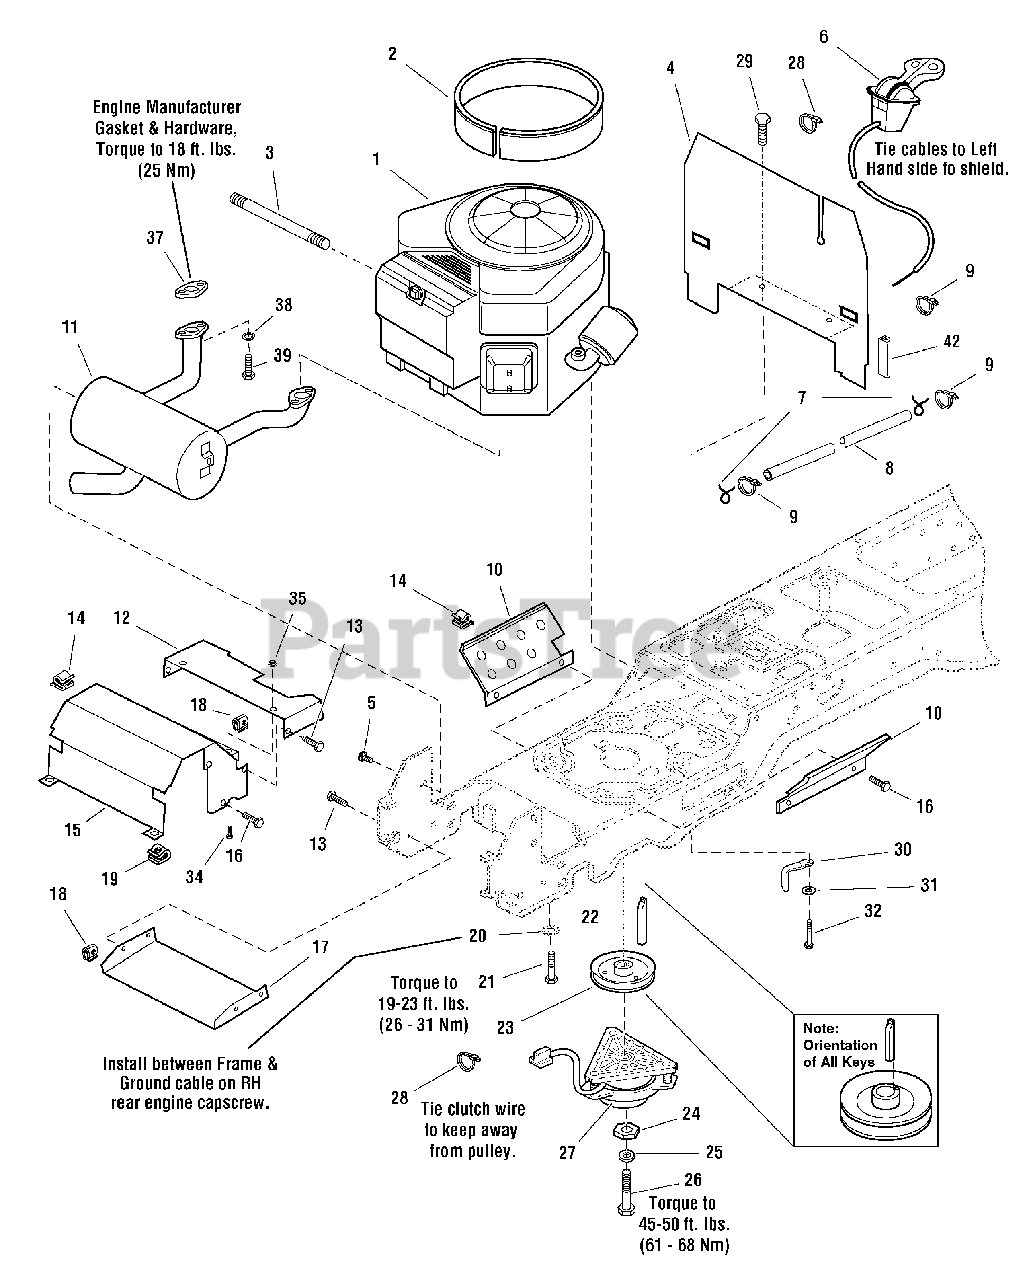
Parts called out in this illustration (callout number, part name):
1	* ENGINE, 24HP Briggs & Stratton Pro Series Twin
1	* ENGINE, 26HP Briggs & Stratton Professional Series
2	EDGING, Airduct
2	SEAL, Foam
3	HOSE, Oil Drain
4	HEAT SHIELD
5	CAPSCREW, Hex Head, Taptite, 5/16-18 x 1/2
6	THROTTLE CONTROL
7	CLAMP, Hose
8	HOSE, Fuel
9	TIE, Self Locking, 7-5/16 Long
10	SHIELD, Side, Heat
11	MUFFLER ASSEMBLY
12	DUCT, Muffler Extension
13	CAPSCREW, Hex, Whiz Lock, 1/4-20 x 5/8
14	CLIP, Wire
15	DUCT, Muffler Top
16	CAPSCREW, Hex Head Taptite, 1/4-20 x 3/8
17	SHIELD, Muffler Bottom
18	NUT, Speed, 1/4-20
19	NUT, Speed, 3/8-18
20	WASHER, Locking, External Teeth, 3/8
21	CAPSCREW, Hex Head, Taptite, 3/8-16 x 1-1/2
22	KEY, 1/4 x 2-1/2
23	PULLEY & HUB ASSEMBLY, Engine
24	WASHER, Hex, 7/16 x 1-1/2
25	WASHER, Locking, 7/16
26	CAPSCREW, Hex Head 7/16-20 x 3-1/2
27	CLUTCH, Electric
28	TIE, Self Locking
29	CAPSCREW, Hex Head Taptite, 1/4-20 x 1/2
30	GUIDE, Belt Retainer, Clutch
31	WASHER, Flat, 3/8
32	CAPSCREW, Hex Head, Taptite, 3/8-16 x 1.5
34	CAPSCREW, Allen Head 1/4-20
35	NUT, Hex Flange, 1/4-20
37	* GASKET
38	LOCKWASHER, 5/16
39	CAPSCREW, Socket Head, 5/16-18 x 7/8, G8
42	EDGING, Rubber
